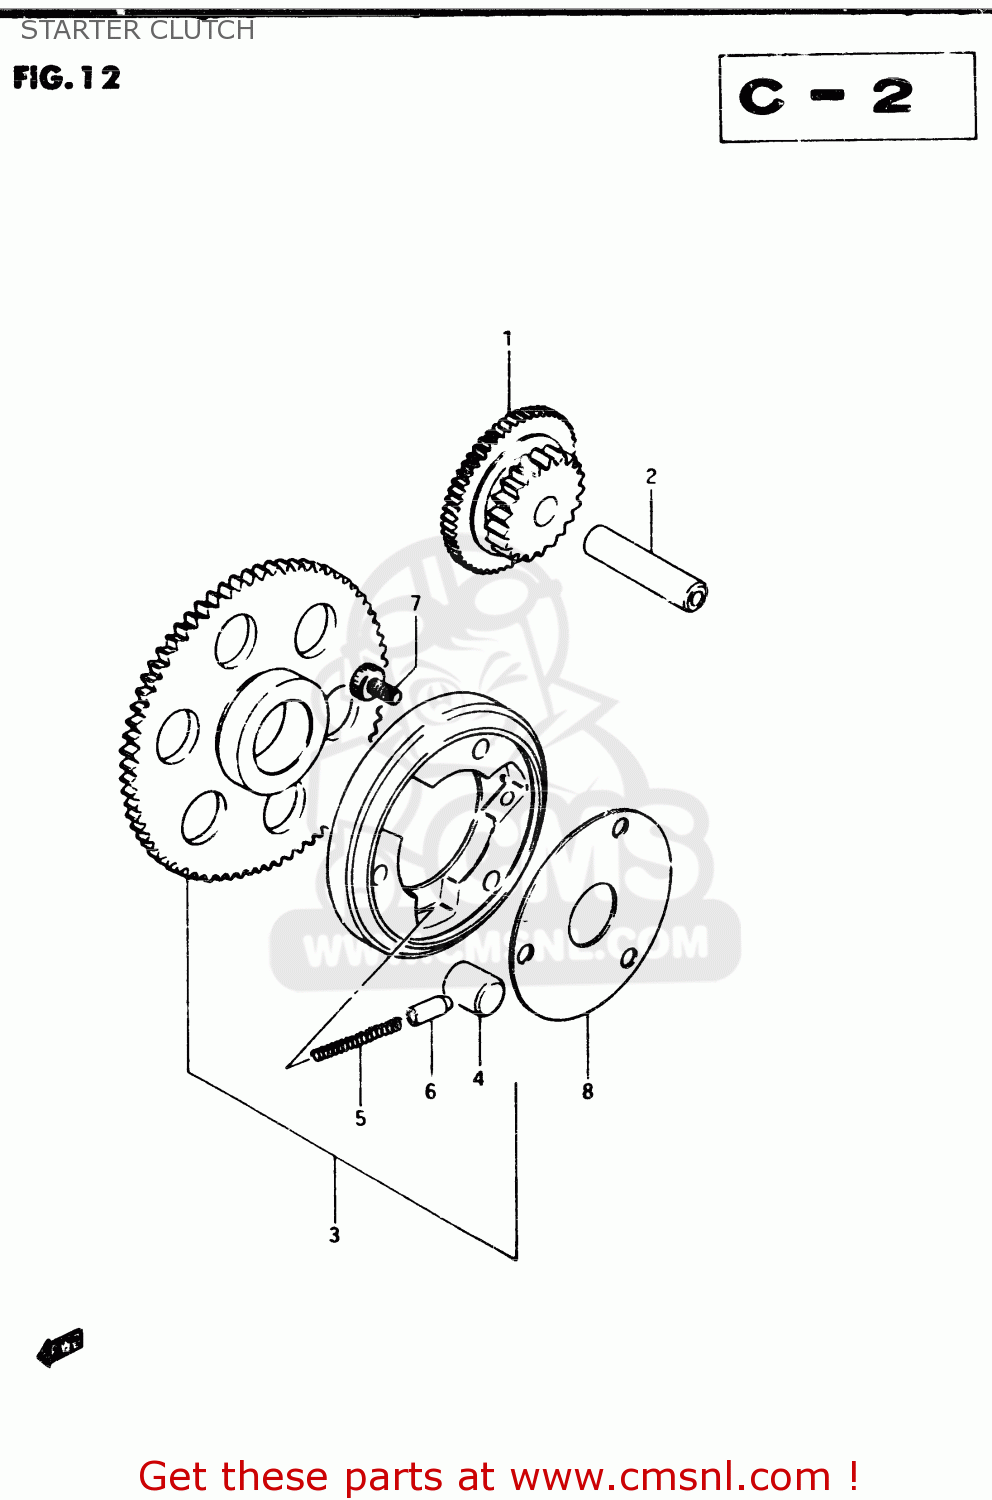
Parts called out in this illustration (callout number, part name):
1	GEAR,STARTER IDLE
2	PIN(7.4X13X40)
3	CLUTCH SET,STARTER
4	ROLLER(15X13)
5	SPRING
6	PIECE,PUSH
7	BOLT
8	SHIM,STARTER CLUTCH HUB
